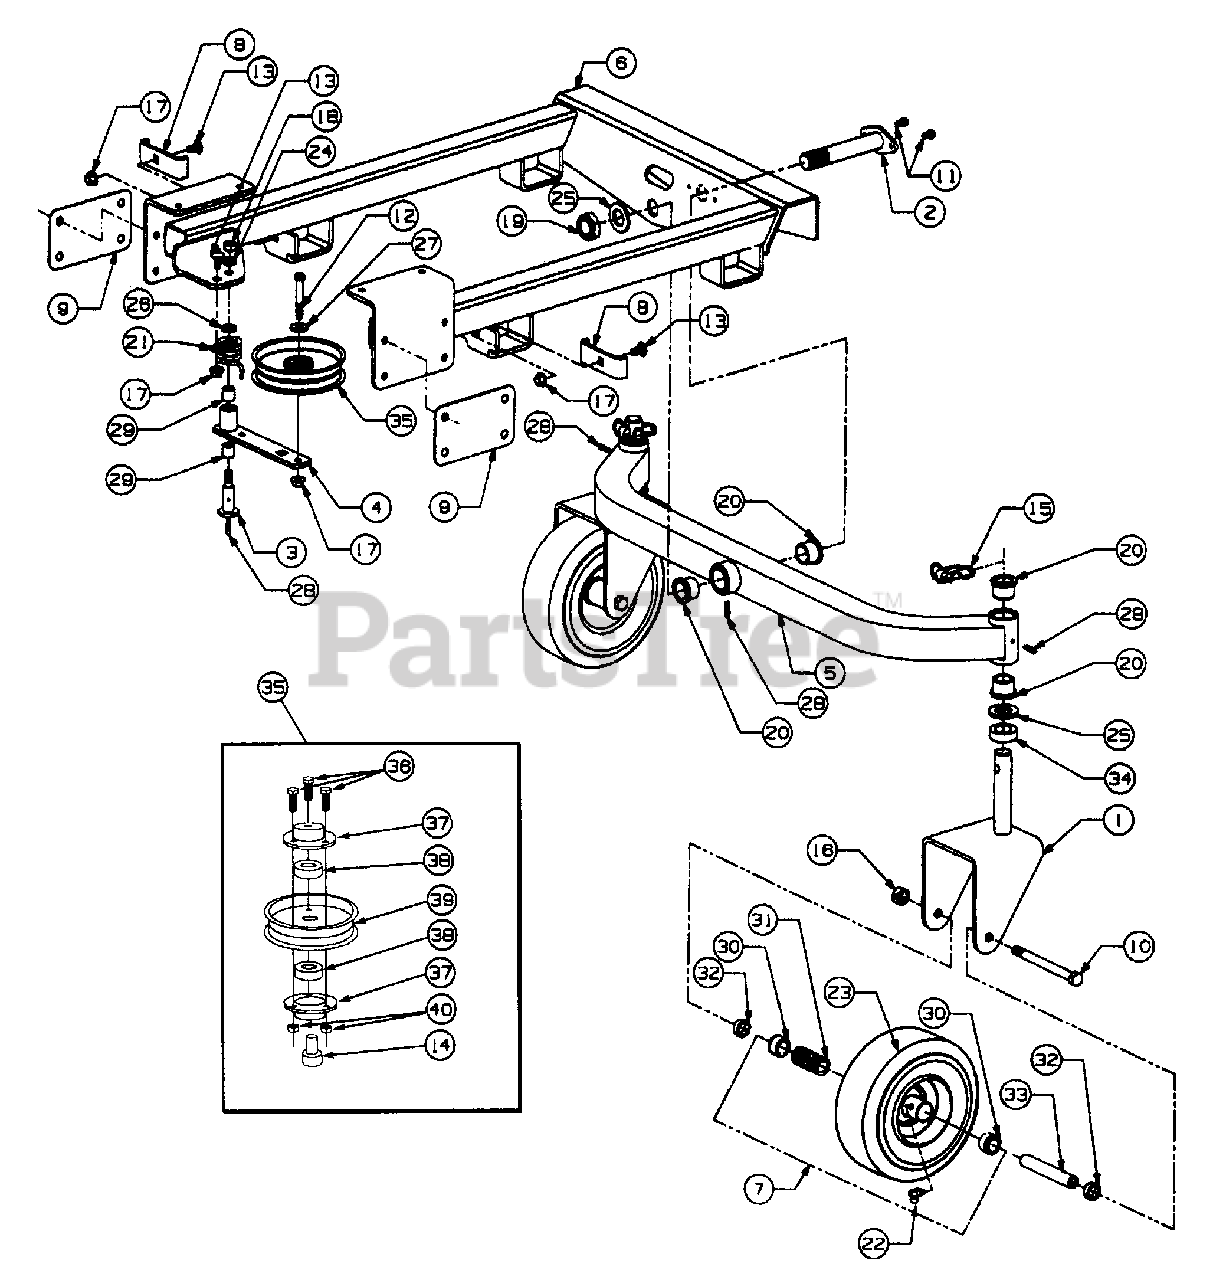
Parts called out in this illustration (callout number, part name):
2	Pin, Axle Pivot
3	Bolt, Shoulder
4	Arm Assy, Idler
5	Axle Assy, Front
7	Wheel Assy, Caster
8	Stop, Wear Bar
10	Screw, Hex Cap, 1/2-20 x 5.50 Lg
11	Screw, Hex Wash Hd TT - Tap 1/4-20 X .50 Lg
12	Screw, Hex Cap, 3/8-16 X 2.5 Lg GR 5
13	Bolt, Sht Nk Carriage 3/8-16 X .75 Lg GR 5
14	Spacer, Shoulder
15	Pin, Klik
16	Nut, Hex Center Lock, 1/2-20
17	Nut, Hex Flanged Lock, 3/8-16
18	Nut, Hex, 7/16-14 GR 5
19	Nut, Hex Lock, 1-14
20	Bearing, Flange
21	Spring, Torsion
22	Fitting, Grease, 90 degree, 1/4-28
23	Tire, Smooth, 9.0 X 3.70 X 4
24	Washer, Lock, 7/16
25	Washer, Special
26	Washer, Flat, .469 X .875 X .105 Thk
27	Washer, Flat, .406 X 1.0 X .105 Thk
28	Fitting, Lube
29	Bearing, Sleeve
30	Bearing, Flange
31	Bearing, Roller
32	Spacer, .790 ID X .347
33	Spacer, Wheel
34	Spacer, 1.015 X 1.62 X .50 Lg
35	Pulley Assy, 5" Idler
36	Screw, Hex Cap, 1/4-20 X .62 Lg GR5
37	Cup, Bearing
38	Bearing, Ball
39	Pulley, 5" Idler
40	Nut, Hex Insert Lock, 1/4-20
